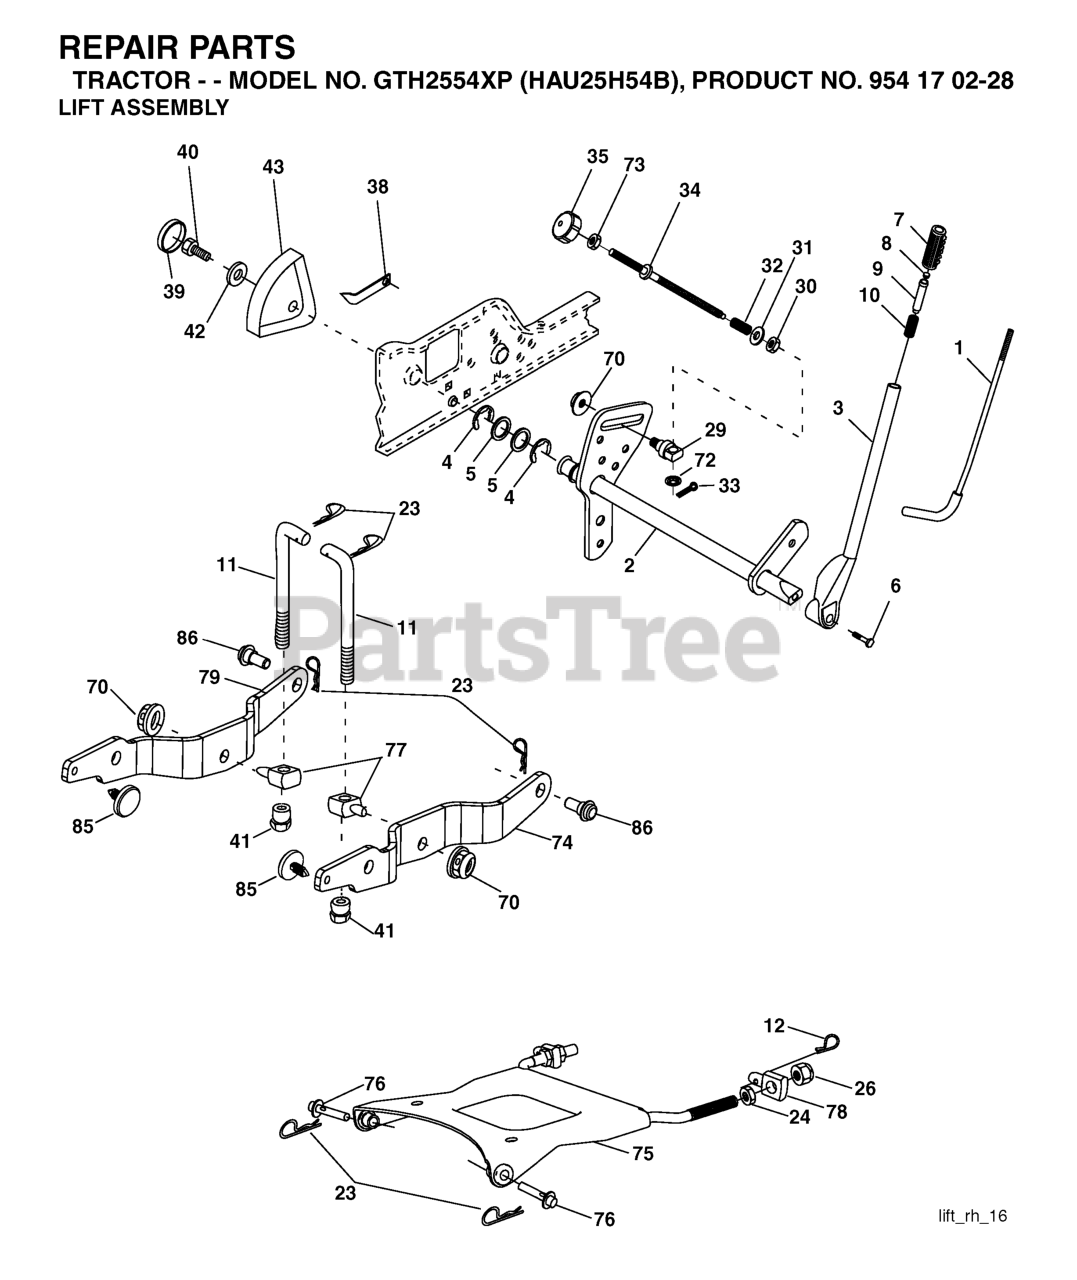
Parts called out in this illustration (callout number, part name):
1	LEVER ROD LT
2	SHAFT ASM., LIFT VGT
3	LEVER ASSY-LIFT RH
5	Washer 29/32 x 1 - 1/4 x 16 Ga.
6	Bolt, Fin Hex 3/8-16 x 1-1/12
7	GRIP HANDLE
8	PLUNGER BUT KIT
9	PLUNGER BUT KIT
10	SPRING 0.620D X 2.125
11	LIFT LINK
12	SPRING RETAINER
23	RETAINER-SPRNG RB
24	NUT.HEX.JAM.1/2-13
26	NUT.LK.W/WSH.1/2.
32	SPRING.COMP.INF.H
33	COTTER PIN
34	ROD.LIFT.ADJUSTABLE
35	KNOB INF 3/8-16
38	POINTER, HEIGHT INDICATOR(2 2)
40	SCREW 5/16-18X1
41	NUT, LIFT LINK 7/16-20
43	HEIGHT INDICATOR
70	NUT
72	NUT PUSH M
73	NUT
74	ARM.SUSP.REAR.RH
75	PLATE ASM SUSP FRONT
76	PIN.FLANGE
79	ARM SUSPENSION LH
85	INSERT WEAR (3 2)
86	BOLT.SHOULDER
